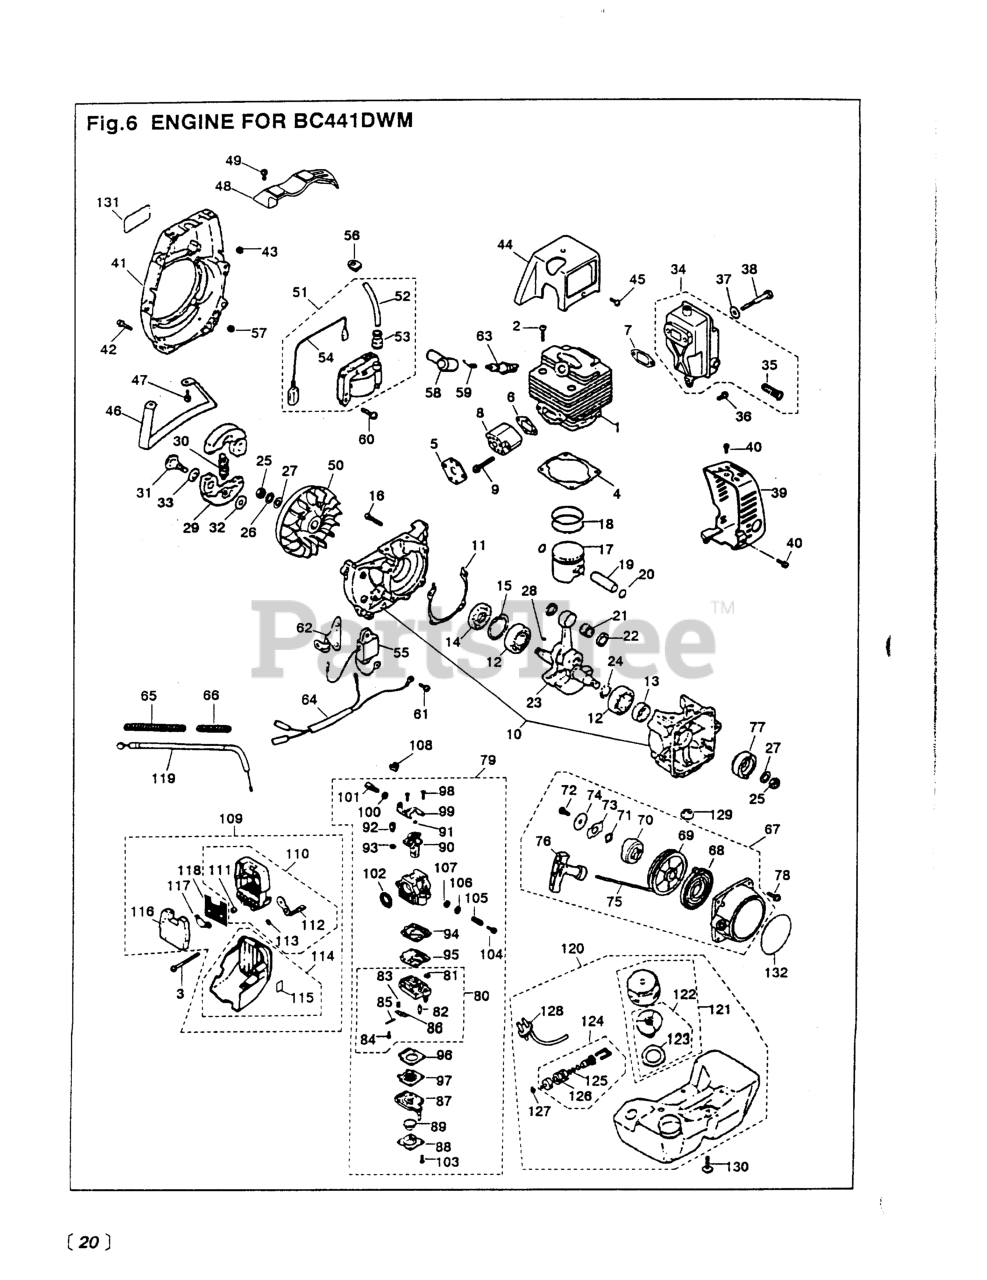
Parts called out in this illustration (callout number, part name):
8	INSULATOR (RPLS -13162)
10	CRANKCASE COMPLETE
13	SEAL, OIL - STARTER SIDE
15	RING, SNAP, M35 X 1.5
16	SCREW, M5 x 30(RPLS 0263-00530
17	PISTON (NLA)
18	RING, PISTON (RPLS -41210)
19	PIN, PISTON
20	RING, SNAP
21	BEARING
22	WASHER (RPLS 1491-41510)
23	SHAFT (RPLS -42001)
24	SHIM (REPLACES 848-870-G000)
26	WASHER, M10 X 25
27	WASHER, M10 x 1.6
28	KEY
31	SCREW
32	WASHER
33	WASHER (USE -51241)
35	ARRESTER
37	WASHER, FLAT (USE 182303)
38	BOLT, M6 x 65
39	COVER
42	SCREW, M5 X 20
46	STAND
49	SCREW (USE 0263-90520 )
51	COIL ASSEMBLY
52	CORD
53	CAP
55	UNIT (RPLS -71310)
58	CAP, PLUG
59	SPRING PLUG (RPLS 3310-71320)
60	SCREW (USE 0263-90520 )
64	CORD COMPLETE
68	SPRING (RPLS -75220)
70	DOG
71	WASHER
72	SCREW
73	RETAINER (RPLS 1861-75161)
74	WASHER
75	ROPE
76	KNOB
77	PULLEY (RPLS -75210)
78	SCREW (USE 0263-90520 )
79	CARBURETOR (RPLS -81001)
80	BODY, PUMP
82	VALVE, INLET
83	SPRING, METERING LEVER
84	SCREW, METERING LEVER PIN
85	PIN, METERING LEVER
86	LEVER
87	BODY, PURGE
88	COVER, PUMP
89	PUMP, PRIMING
90	VALVE ASSEMBLY
92	SWIVEL
93	RING
94	GASKET, PUMP
95	DIAPHRAGM
96	GASKET, DIAPHRAGM
97	DIAPHRAGM (USE 4810-81260)
98	SCREW
100	NUT, CABLE ADJUSTER
101	SCREW, CABLE
102	RING, PACKING
103	SCREW
108	CAP, CABLE END
111	SLEEVE
114	COVER, AIR FILTER (RPLS -82201
115	LABEL
117	PLATE
119	CABLE COMPLETE
122	VALVE COMPLETE
123	PACKING (RPLS -85321)
124	FILTER ASSY
127	CLIP (REPLACES 2841-31280)
128	PIPE ASSY (RPLS -85800)
130	SCREW
